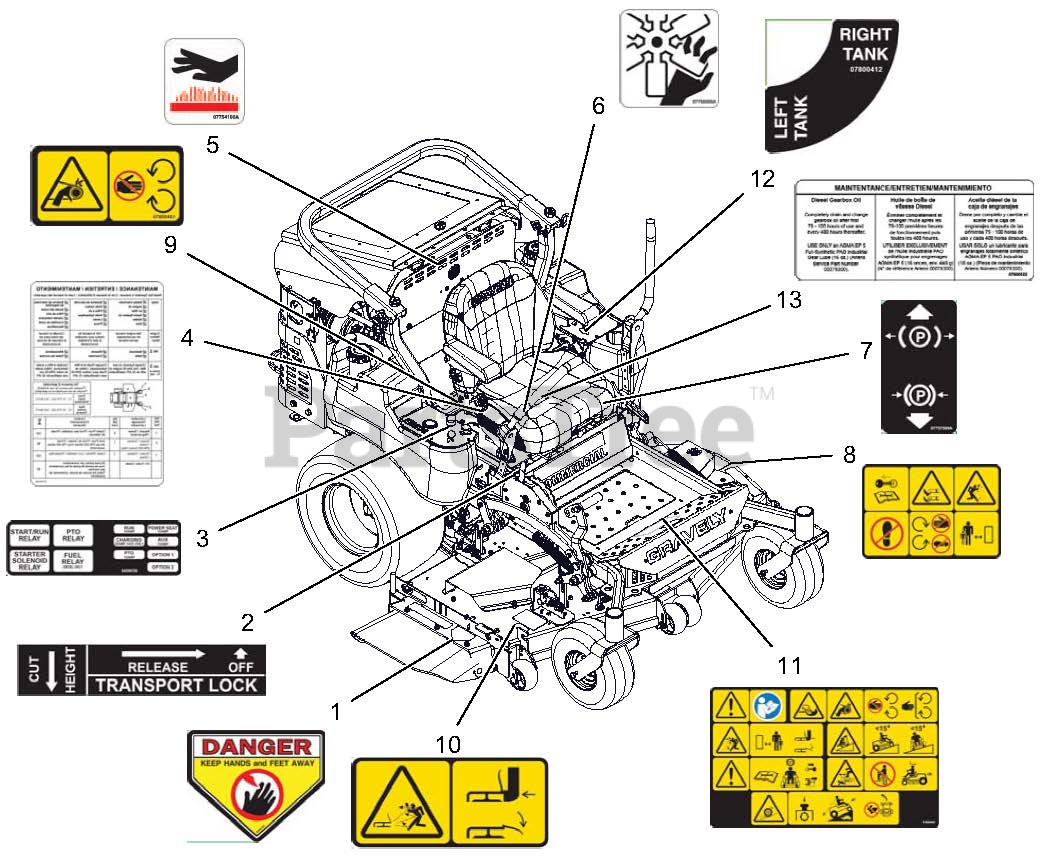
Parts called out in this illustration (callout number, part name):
1	DECAL, DANGER
2	DECAL, TRANSPORT LOCK INSTRUCT
3	DECAL, FUSE BOX
4	DECAL, MAINTENANCE
5	DECAL HOT SURFACE
6	DECAL, DANGER - FAN
7	DECAL, PARKING BRAKE LEVER
8	DECAL, SAFETY - MOWER DECK
9	DECAL, SAFETY - GUARDING
10	DECAL, SAFETY - DECK GUARDING
11	DECAL, MAIN SAFETY, COMMERCIAL
12	DECAL, DIESEL FUEL VALVE
13	DECAL, DIESEL GEARBOX MAINTENANCE
